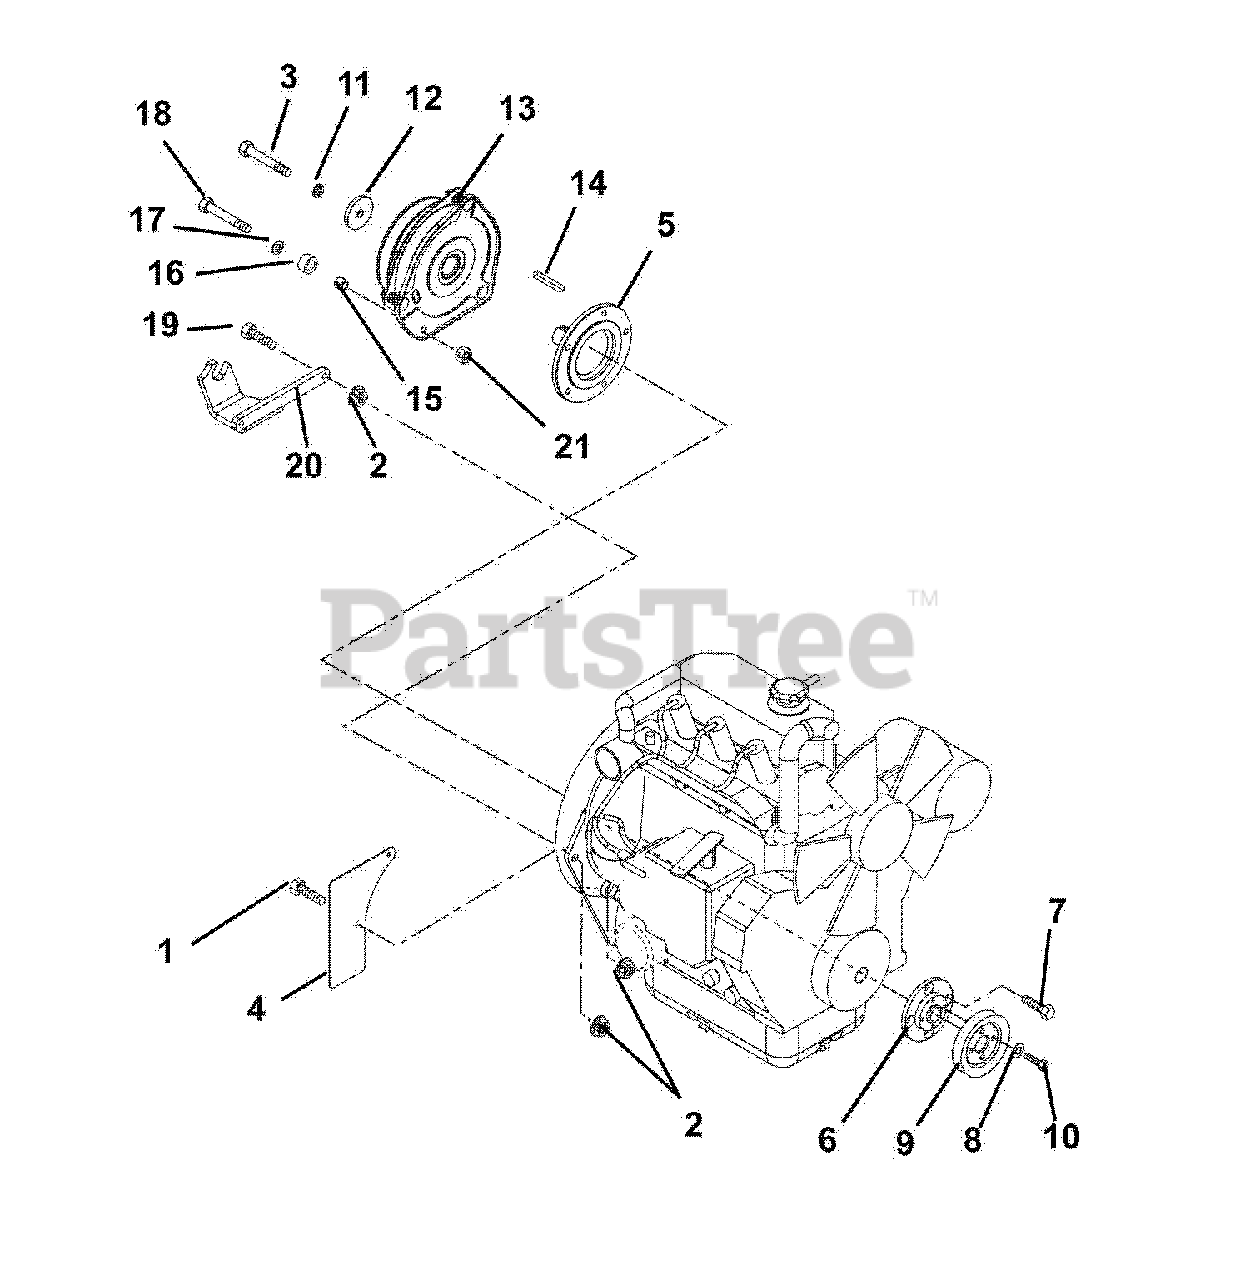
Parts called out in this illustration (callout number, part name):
1	Bolt, Hex .31 -18 x .75 Grade 5
2	Nut, Locking Top Flange .31-18
3	Bolt, Hex .44-20 x 2.50 Grade 5 YZ EP80
4	Guard, Flywheel
5	Stub Shaft
6	Adapter, Sheave
7	Bolt, M8-1.25 x 25
8	Washer, Locking .25 x .062
9	Sheave, Poly-V 1.0 x 3.25
10	Bolt, Hex .25-20 x .75 Grade 5
11	Washer, Locking .44 x .109 Regular
12	Washer, Flat Steel .469 x 2.00 x .25
13	Clutch, Ogura
14	Key .25 x .25 x 2.25
15	Spacer .375 x .686 x .516 Steel
16	Bumper, Rubber .62 x 1.0 x .51
17	Washer, Flat Steel .406 x .812 x .065
18	Bolt, Hex .38-16 x 1.00 Grade 5
19	Bolt, Hex .31-18 x 1.25 Grade 5
20	Bracket, Clutch Stop
21	Nut, Hex Jam .375-16
